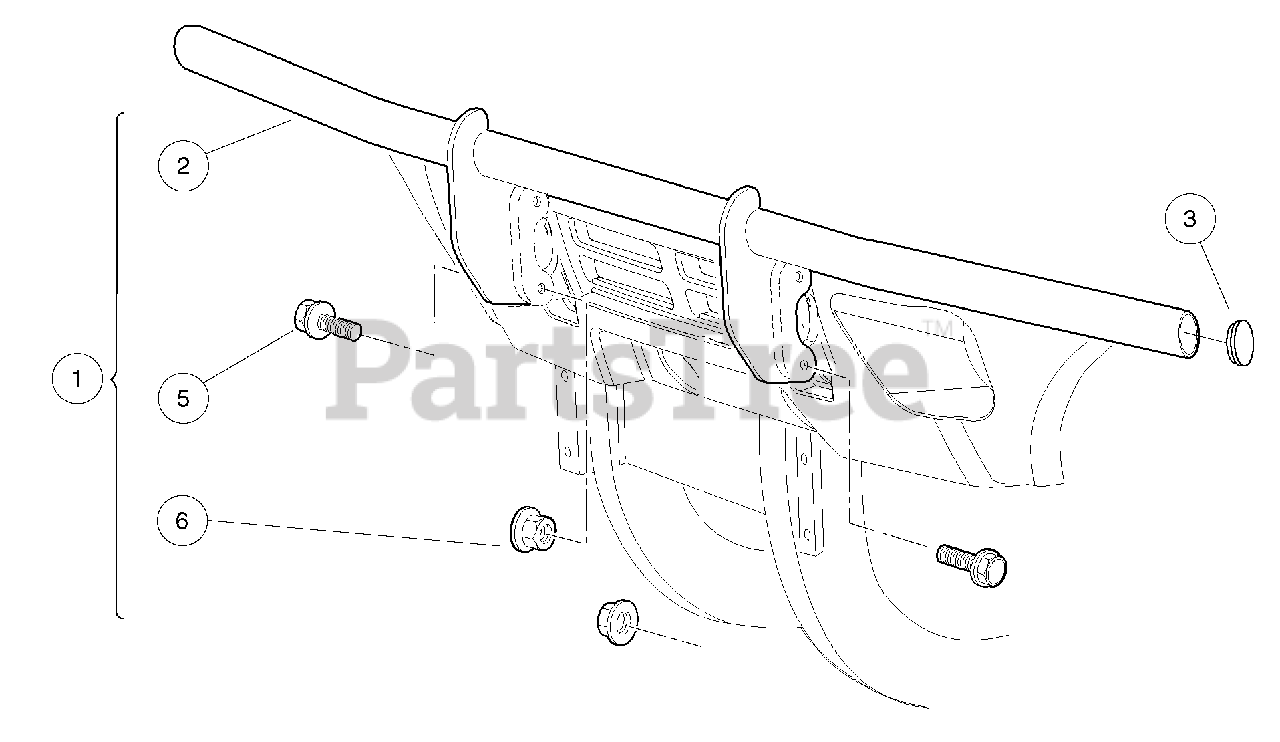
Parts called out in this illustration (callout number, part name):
1	Kit, Tube Bumper CCI
2	Weldment, Frt Bumper, Restyle
3	Plug, Tube, Round, 1-3/4"
4	Instructions, Brushguard/Bumper
5	Screw, M10 X 1.25 X 30 Hex Blk
6	Nut, Flg, M10 X 1.25 Hex Blk
